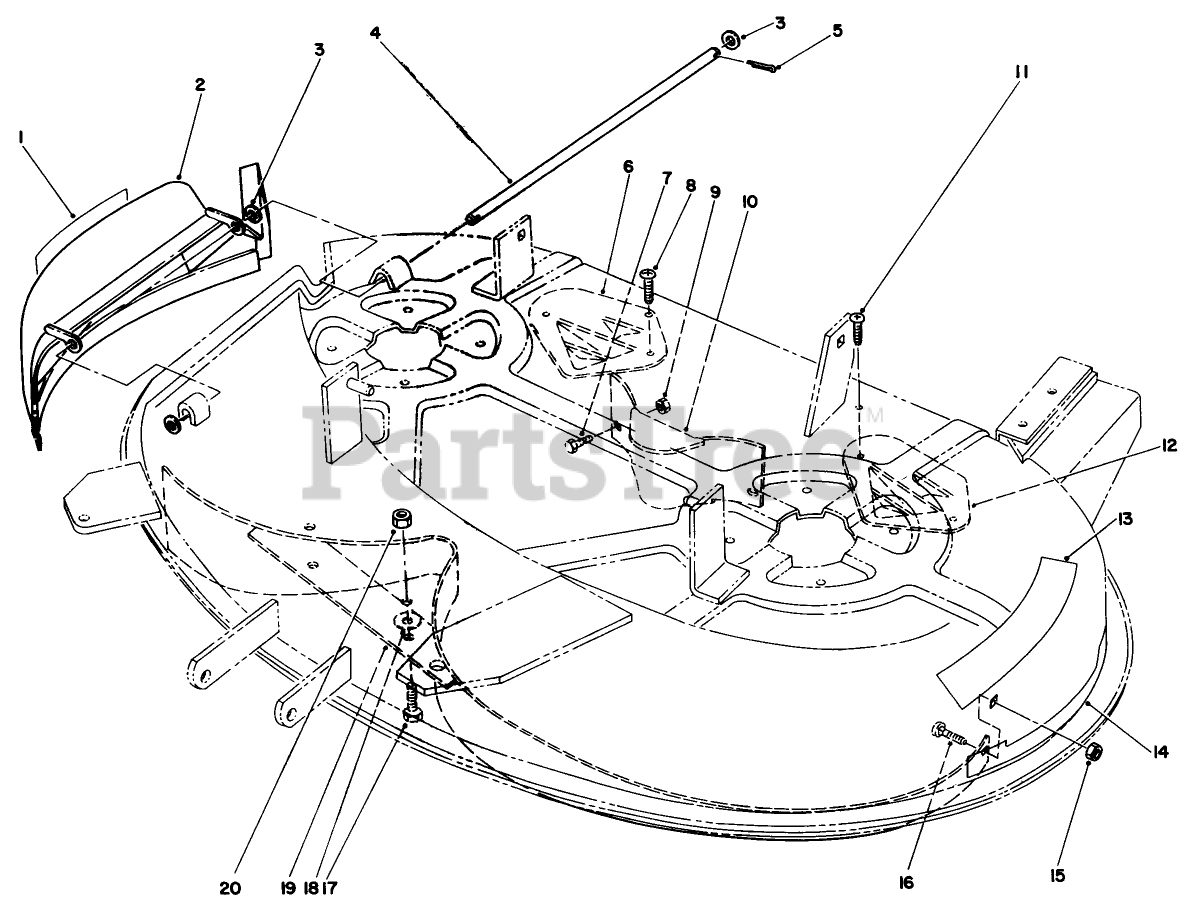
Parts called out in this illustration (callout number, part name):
1	DECAL-DANGER, THROWN OBJECT
2	Chute-Recycler
3	WASHER 5/16 SAE
5	Cotter Pin
6	KICKER
7	H H C S
8	SCREW-PPH, PLASTITE
9	Nut
10	Baffle-Rear
11	#8 X .625" PHILPS PAN H
12	PLATE-KICKER
13	DECAL-DANGER
14	DECAL-38" RECYCLER
15	Nut
16	Bolt
17	Bolt
18	WASHER
19	Baffle-38"
20	NUT
